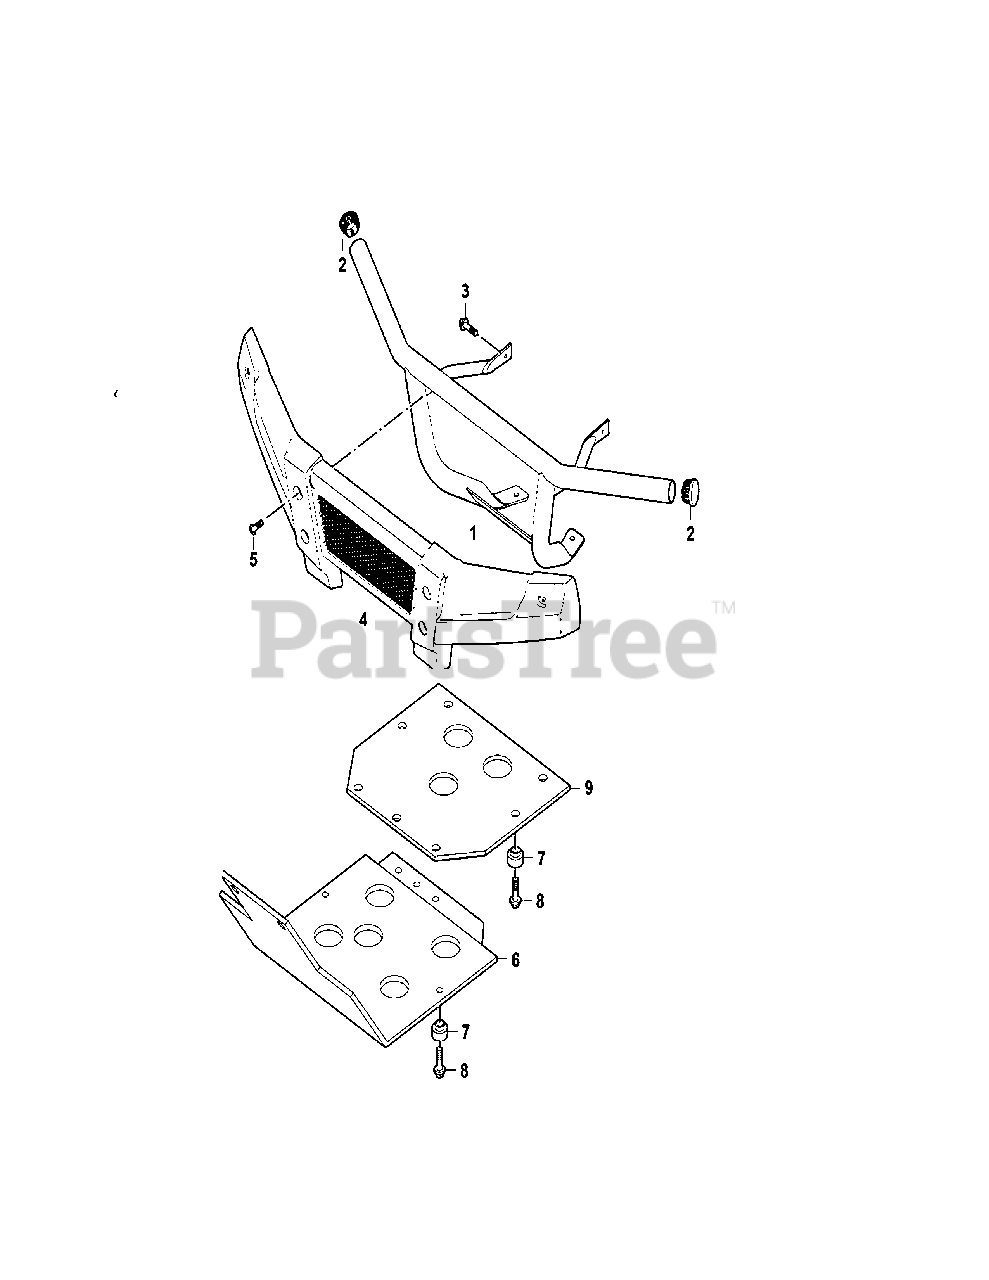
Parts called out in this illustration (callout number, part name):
1	Front Bumper
2	Bumper Pipe Plug I
3	Hexagon flange bolt M10×1.25×20
4	Protective Cover,Front Bumper
5	Cross large plate head screw M6×16
6	Protective plate, front bumper
7	Cap washer
8	Hexagon Flange Bolt M6×16
9	Rear lower protective plate
